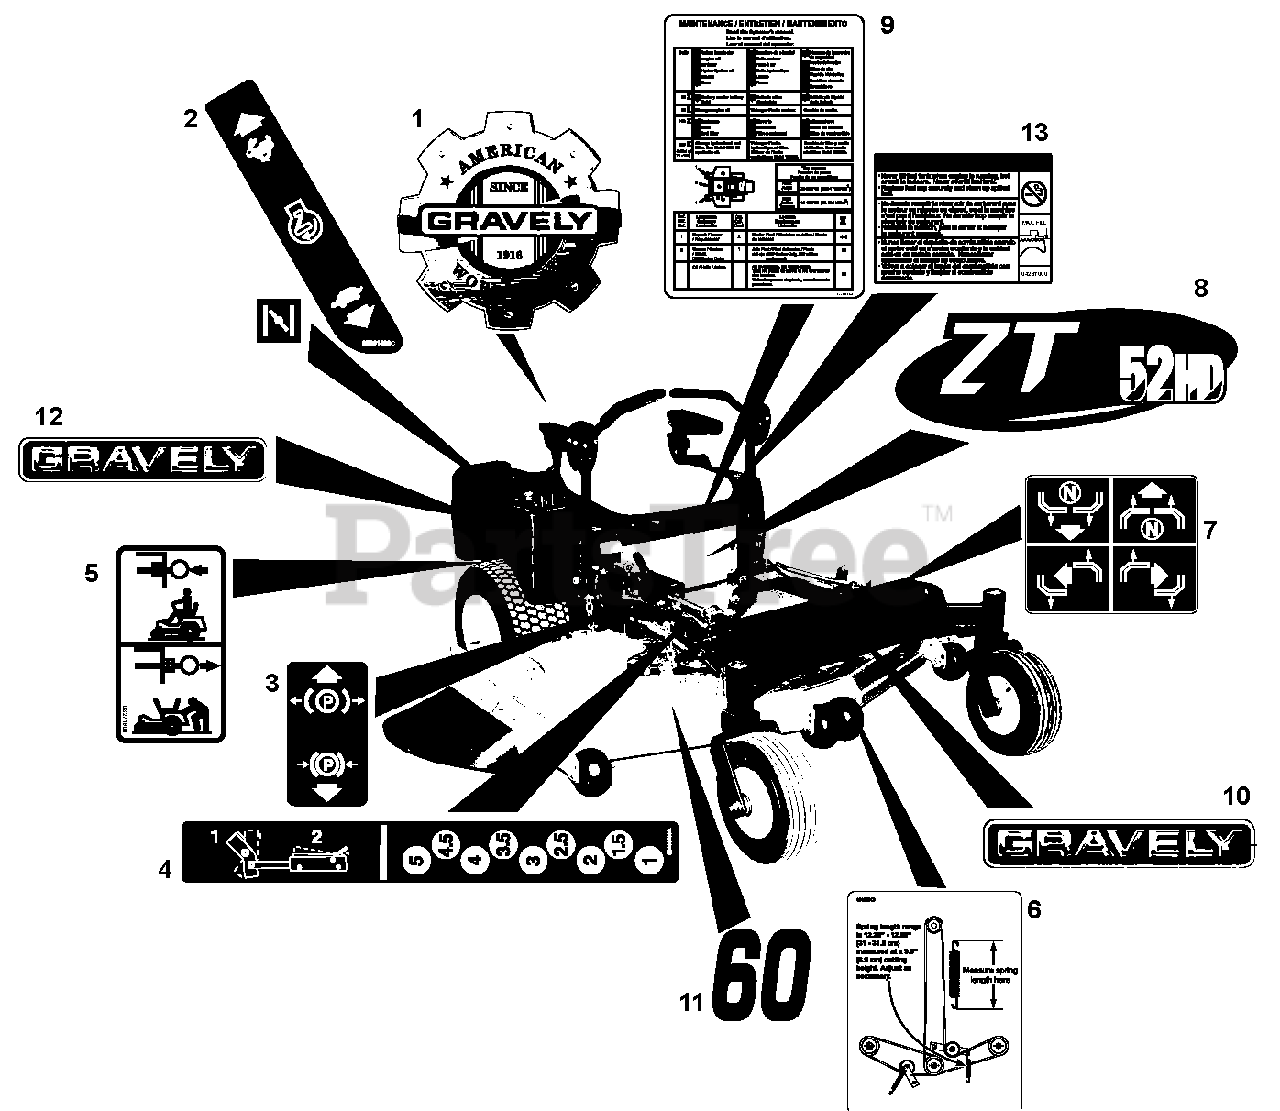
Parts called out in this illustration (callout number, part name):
1	Decal, Gravely Heritage Small
2	Decal, Control
3	Decal, Parking Brake Lever
4	Decal, Height of Cut
5	Decal, Transmission Disconnect
6	Decal, Belt Diagram
7	Decal, Instructional Steering
8	Decal, 44 HD (991090, 098)
8	Decal, 48 HD (991082, 099)
8	Decal, 52 HD (991083, 100)
8	Decal, 60 HD (991084, 101)
9	Decal, Maintenance Instructions
10	Decal, 15" Gravely Logo
11	Decal, 60" (991084, 101)
11	Decal, 52" (991083, 100)
11	Decal, 48" (991082, 099)
11	Decal, 44" (991090, 098)
12	Decal, Fuel Tank Gravely
13	Decal, Fuel Warning
